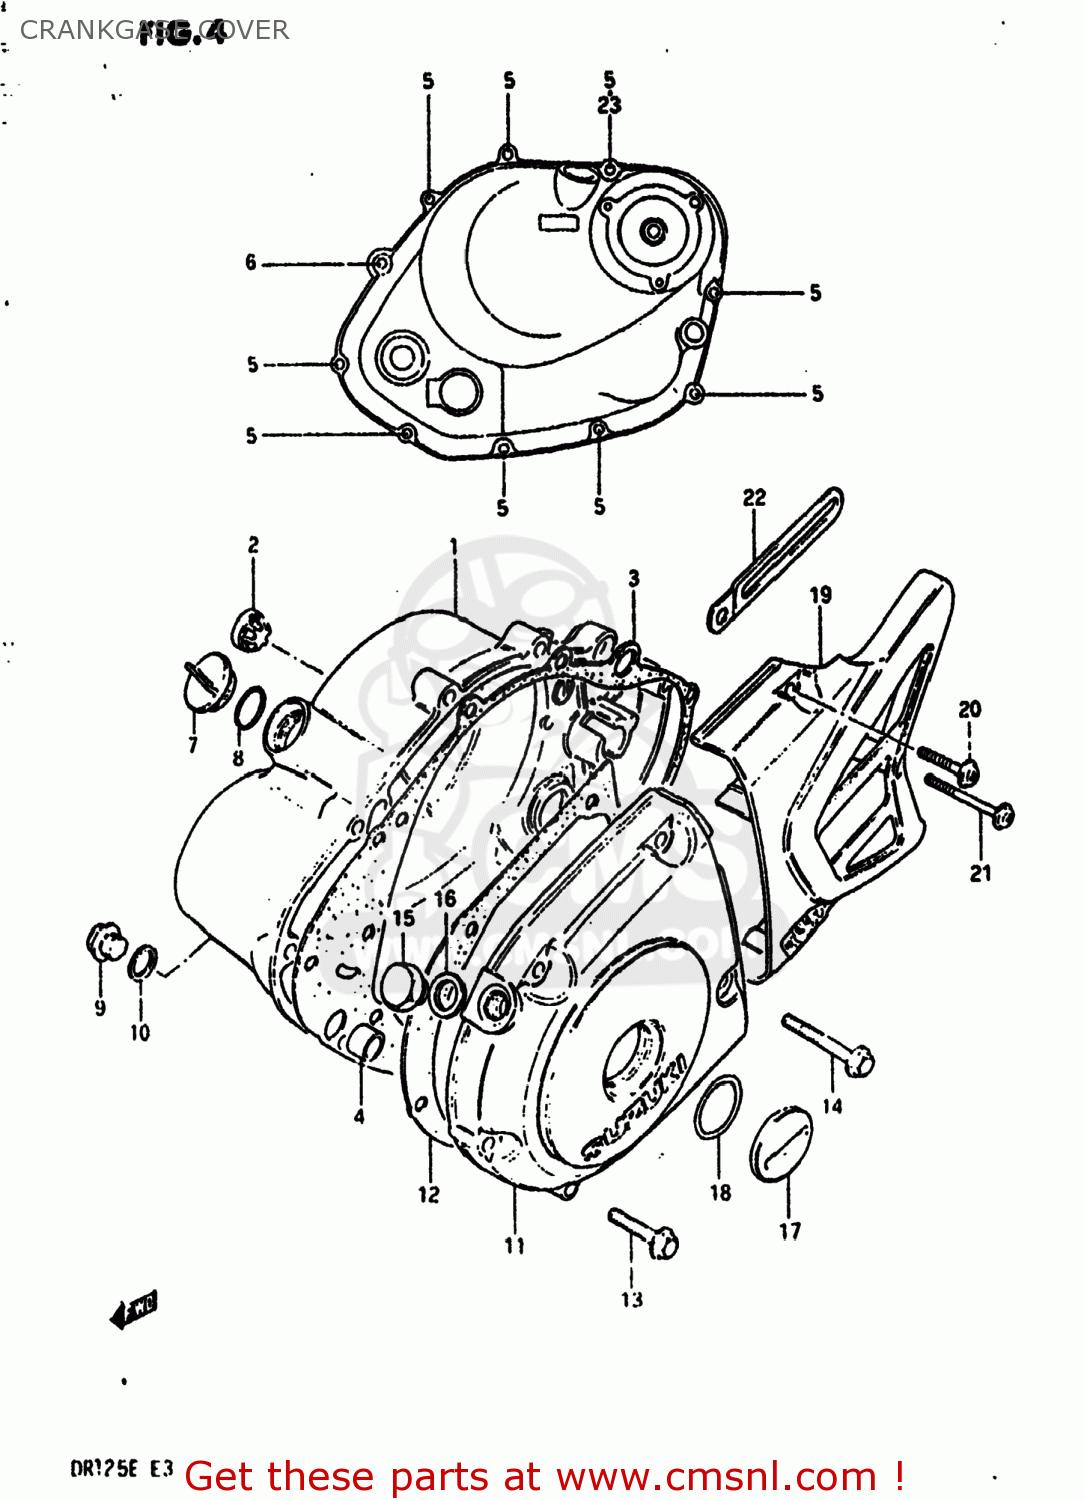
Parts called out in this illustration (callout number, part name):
1	COVER,CLUTCH
2	LENS,OIL LEVEL CHECK
3	GASKET,CLUTCH COVER (MCA)
4	PIN
5	BOLT (6*30)
6	BOLT (6X45)
7	PLUG
8	O RING(D:3.1,ID:16.8)
9	PLUG(14X12)
10	GASKET(14X19.2X2) (NAS)
11	COVER,MAGNETO
12	GASKET,MAGNETO COVER (MCA)
13	BOLT (6*30)
14	BOLT (6X40)
15	PLUG(12X9)
16	GASKET(12.1X16.2X3.7) (NAS)
17	PLUG
18	O RING(D:3.1,ID:22.7)
19	COVER,SPROCKET
20	SCREW
21	SCREW
22	CLAMP
23	WASHER
